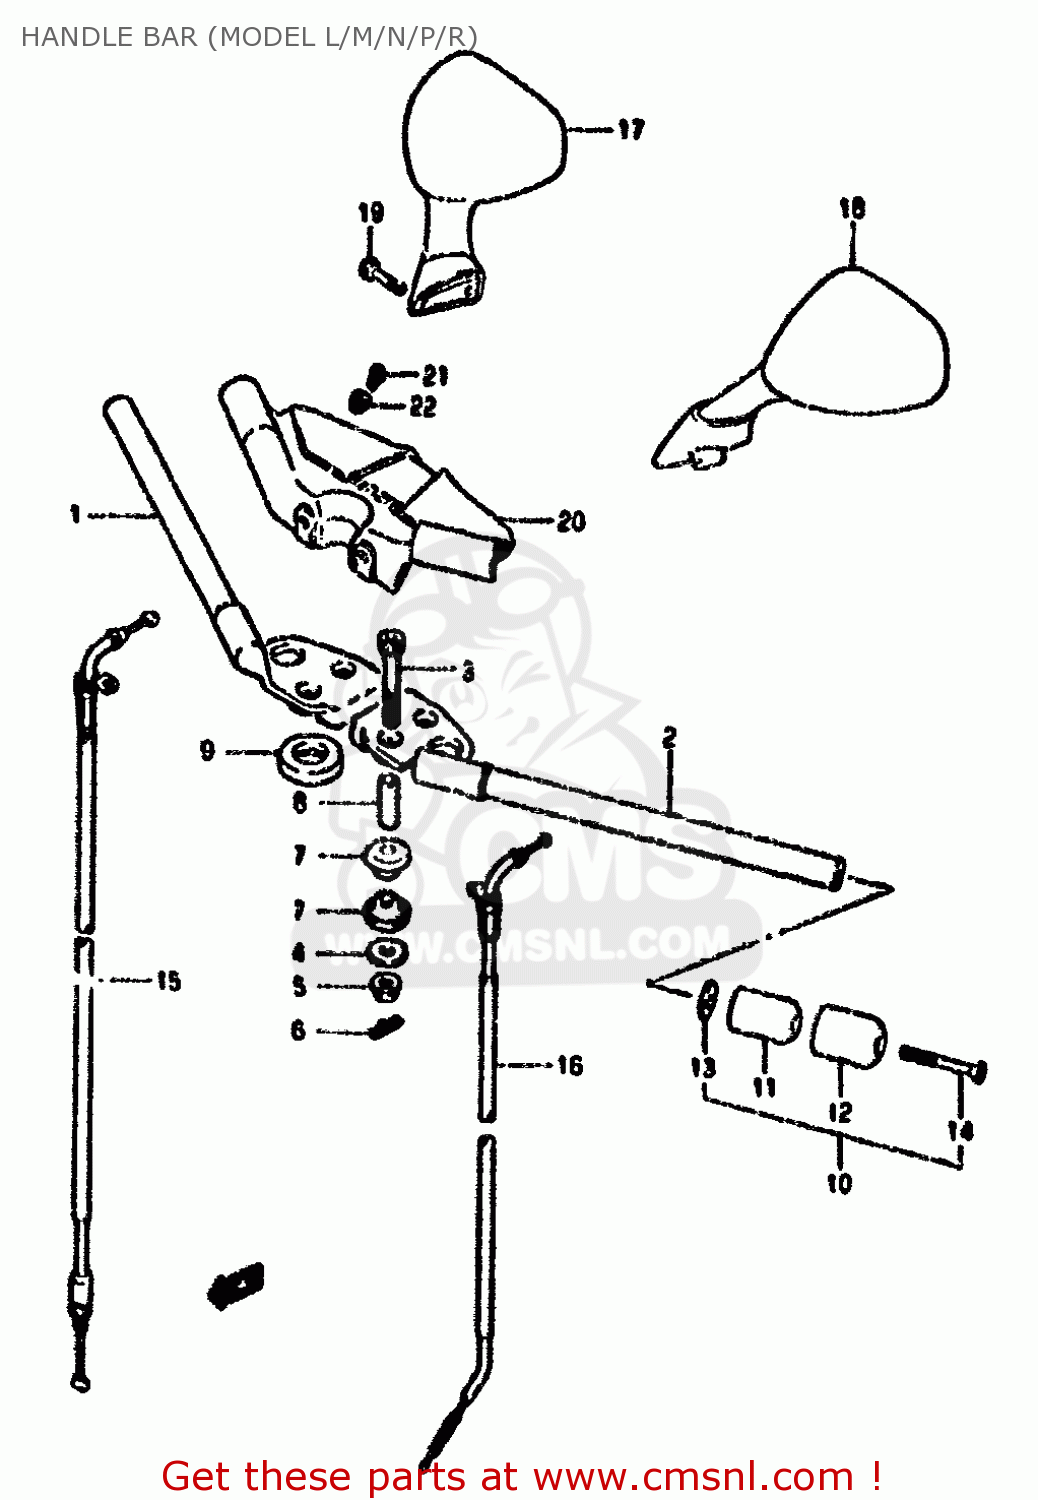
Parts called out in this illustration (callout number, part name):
1	HANDLEBAR,RIGHT
2	HANDLEBAR,L
3	BOLT L:70
4	WASHER
5	NUT 10MM
6	CLIP
7	RUBBER,HANDLE HOLDER
8	SPACER
9	CUSHION,HANDLE INNER CAP
10	BALANCER SET,HANDLEBAR
11	BALANCER,HANDLEBAR
12	CAP,BALANCER
13	SPACER,BALANCER
14	SCREW
15	CABLE ASSY,THROTTLE
16	CABLE ASSY,STARTER
17	MIRROR ASSY,RR VIEW,R
18	MIRROR ASSY,RR VIEW,L
19	BOLT
20	COVER,HANDLE
21	SCREW 5X12
22	MIRROR ASSEMBLY,REAR VIEW,LEFT
23	PLUG ,6X20
24	COVER,HANDLE
25	SCREW, FRONT & REAR
26	WASHER
